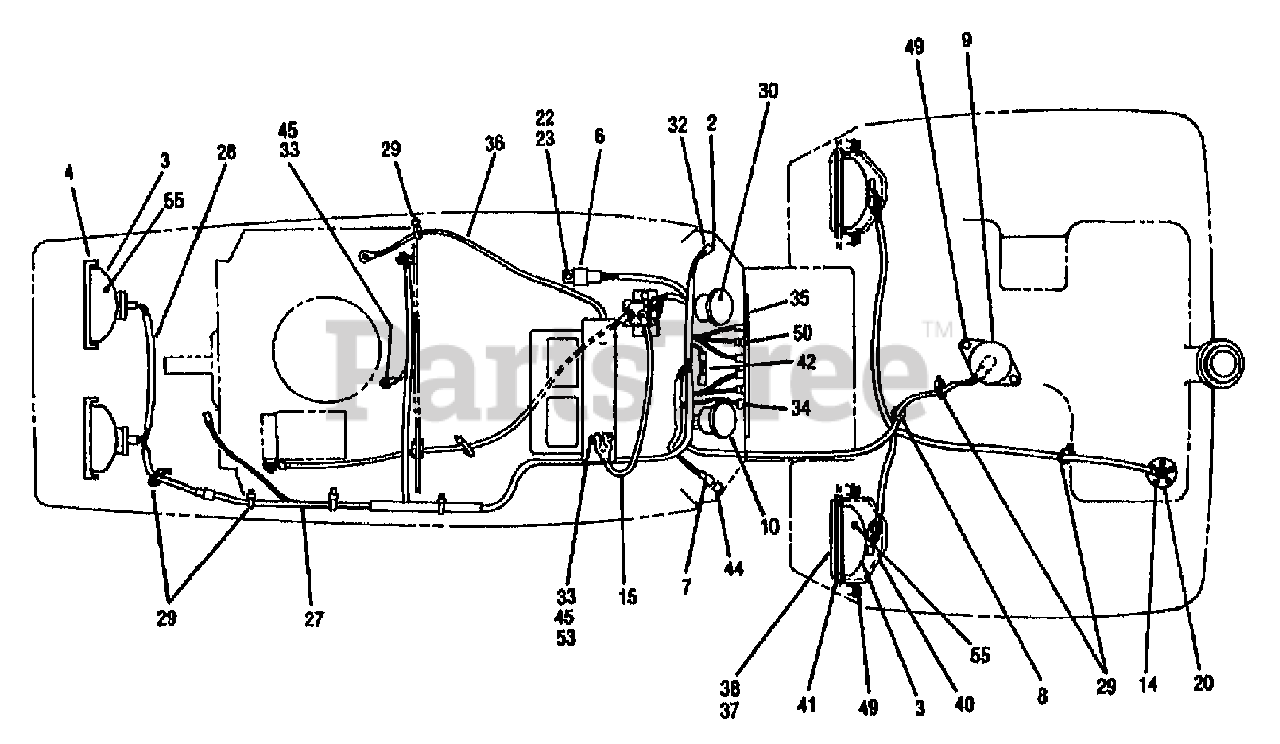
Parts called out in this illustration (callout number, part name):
2	SCR-FHP #6-32X.50 ZP
3	ASSM-LIGHT
3	SOCKET
4	RETAINER
6	RELAY-SPEED CONTROL
7	SWITCH-LIGHT
8	GROMMET-RUBBER
9	SWITCH-SEAT
10	METER-HOUR
15	CABLE-BATTERY (+)
20	SENDER-FUEL
22	SCR-TRUSS #10-24 X 5/8
23	NUT W/LKWASHER 10-24 ZP
27	HARNESS-WIRE
28	HARNESS-HEADLIGHT
29	TIE-CABLE NYLON BLACK
30	GAUGE-FUEL {13062}
32	SWITCH-PTO
33	SCR-HH 1/4-20X.625 G5 ZP
34	BULB (MFG NO. GE 73)
35	LENSE
36	CABLE (-)
37	LENSE-LH
38	LENSE-RH
40	SHIELD-STONE
41	GASKET
42	SENSOR-VOLTAGE
44	SWITCH-SPEED CONTROL
45	WASHER-LK .25 ZP
49	SCR-PHP 1/4-20X.50 ZP
50	SCR-PHP M6-32X.38 ZP
53	NUT-HEX 1/4-20 ZP
55	LIGHTBULB
